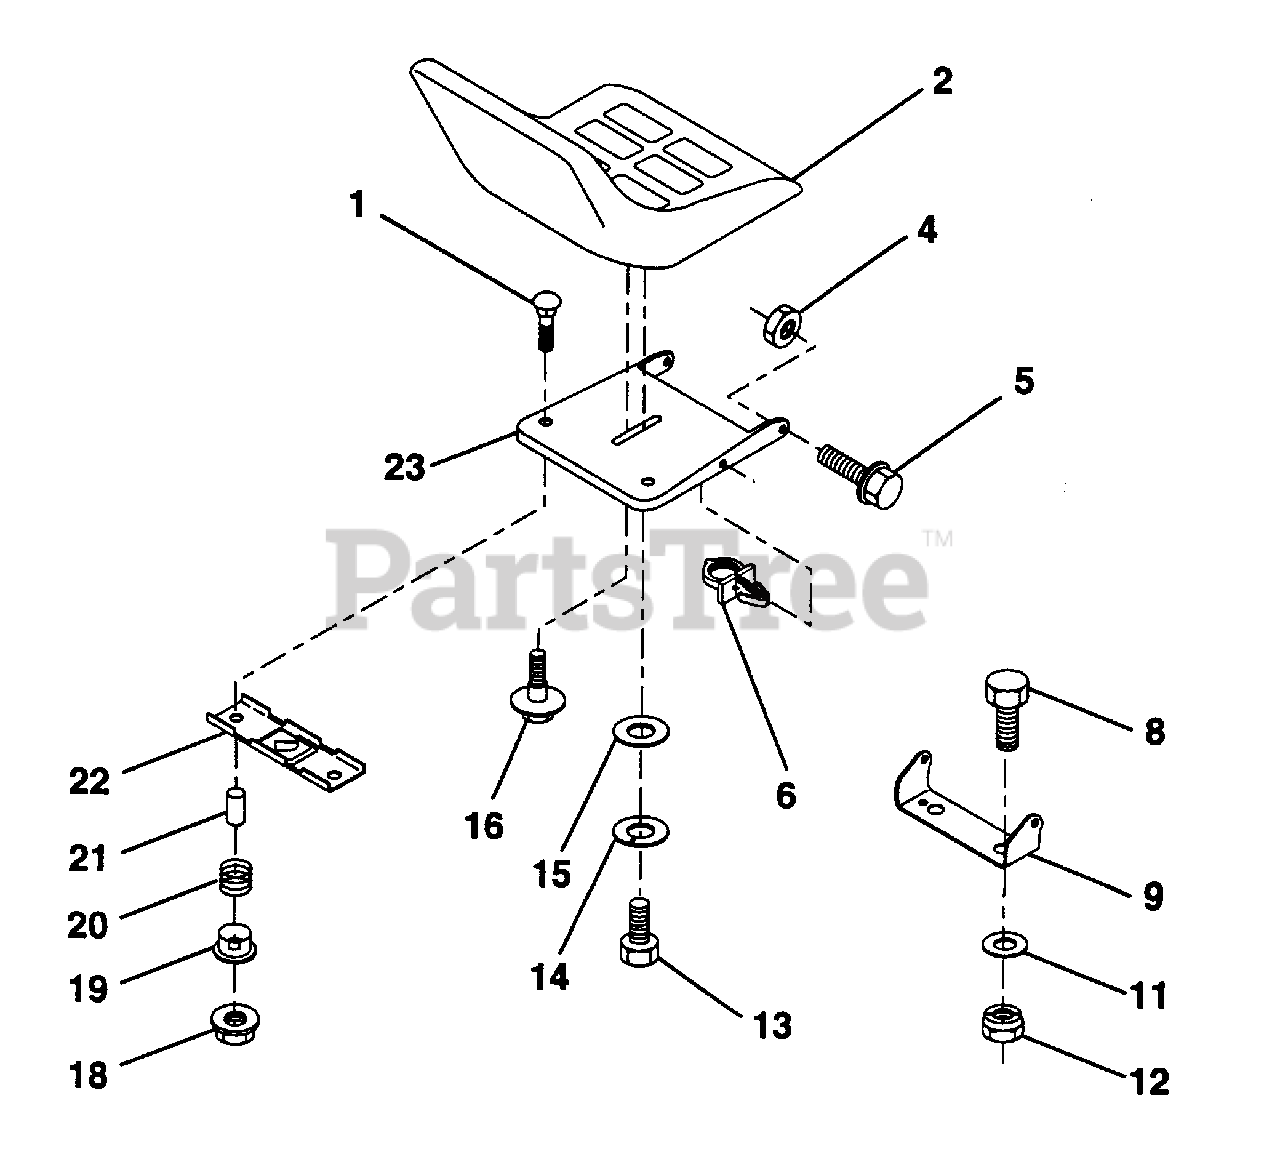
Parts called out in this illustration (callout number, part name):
1	Bolt, Carriage 1/4-20 x 1-3/8
2	Seat (AYP part number)
4	Locknut, Hex w/Ins 5/16-18 (AYP part number)
5	Bolt, Shoulder 5/16-18 UNC (AYP part number)
6	Clip, Push-In Hinged (AYP part number)
8	Bolt, Fin Hex 3/8-16 UNC x 1 (AYP part number)
9	Bracket, Pivot Seat (AYP part number)
11	Washer 12/32 x 2 x 10 Ga. (AYP part number)
12	Nut, Lock Hex w/Wsh 3/8-16 (AYP part number)
13	Bolt Hex 1/2-13 x 7/8 (AYP part number)
14	Washer Lock Hvy. Hlicl Spring 1/2 (AYP part number)
15	Washer, 17/32 x 1-3/16 x 12 Ga. (AYP part number)
16	Bolt, Shoulder (AYP part number)
18	Nut, Hex Large Flange Lock (AYP part number)
19	Bushing, Snap (AYP part number)
20	Spring, Compression (AYP part number)
21	Spacer, Split 28 Id. x .88 Lg. (AYP part number)
22	Bracket, Switch, Mounting (AYP part number)
23	Pan, Seat (AYP part number)
